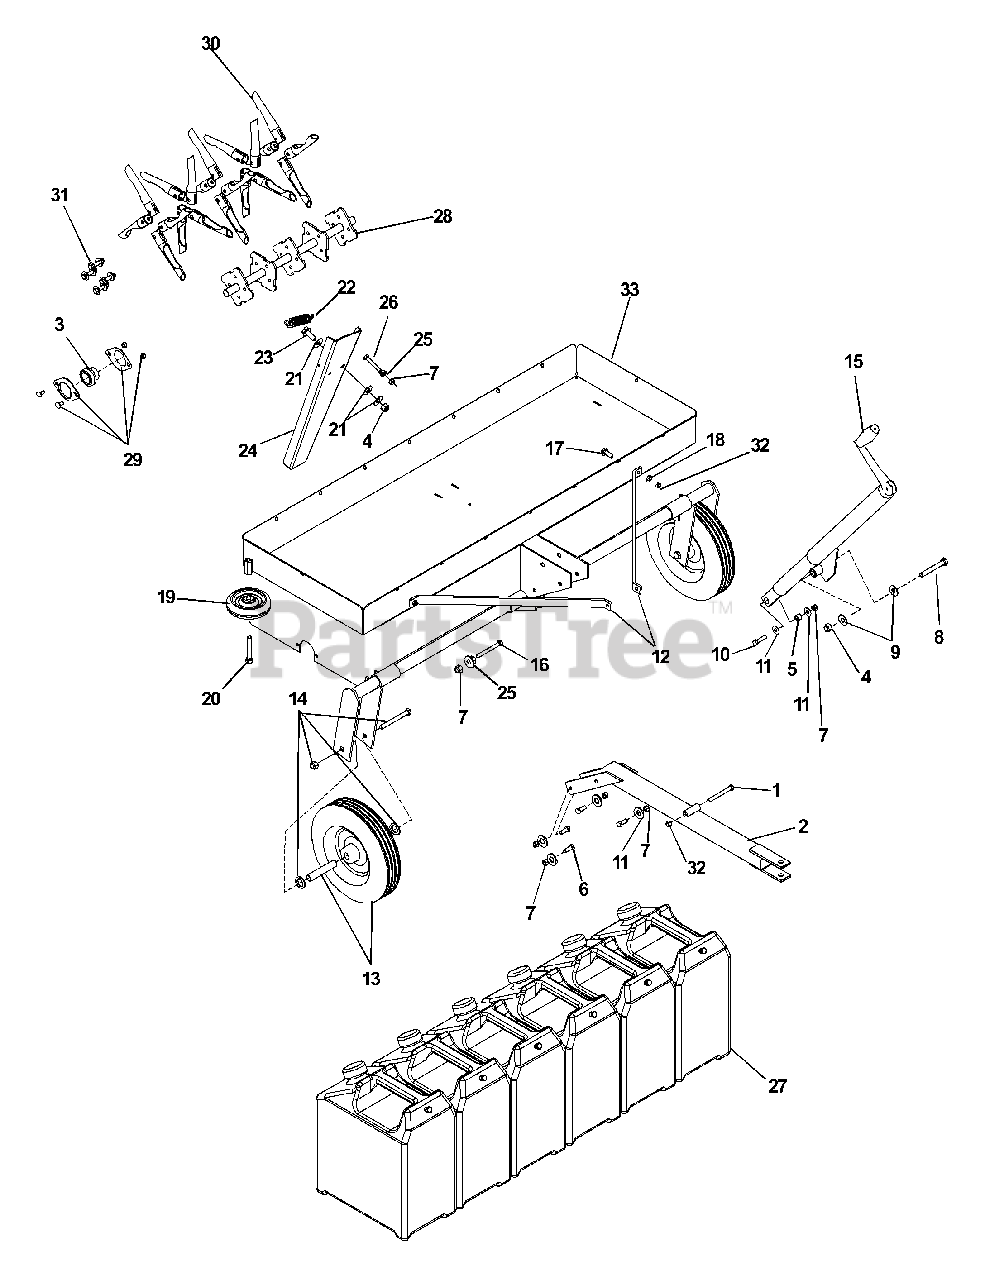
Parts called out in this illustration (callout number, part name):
1	HCS 5/16-18 X 3, GR5
3	BEARING W/LOCK COLLAR
4	NUT, 1/2-13, NYLOC
5	AXLE PIVOT BUSHING
6	HCS 3/8-16 X 1 GR5
7	NUT, 3/8-16, NYLOC
8	HCS 1/2-13 X 3 1/2, GR5
9	WASHER, 1/2
10	HCS 3/8-16 X 1 3/4, GR5
11	WASHER, 3/8
13	WHEEL ,12" X 3" W/ROLLER BEARING
14	BOLT KIT FOR WHEEL
15	JACK
16	HCS 3/8-16 X 3 1/2, GR8
17	RHSNB 5/16-18 X 1
18	WASHER, 5/16
19	TILT WHEEL
20	HCS 1/2-13 X 3, GR5
21	WASHER, 7/16
23	FLANGE HEAD BOLT, 1/2-13 X 1 1/4
25	NUT, 3/8-16, WHIZLOCK, GR5
26	HCS 3/8-16 X 2 1/4, GR5
27	WATER TANKS (SET OF 6)
28	ROTOR
29	STAMPING KIT, FOR 1" BEARING
30	TINE SET (20 TINES)
31	FASTENER KIT, ONE ROTOR
32	NUT, 5/16-18, NYLOC
